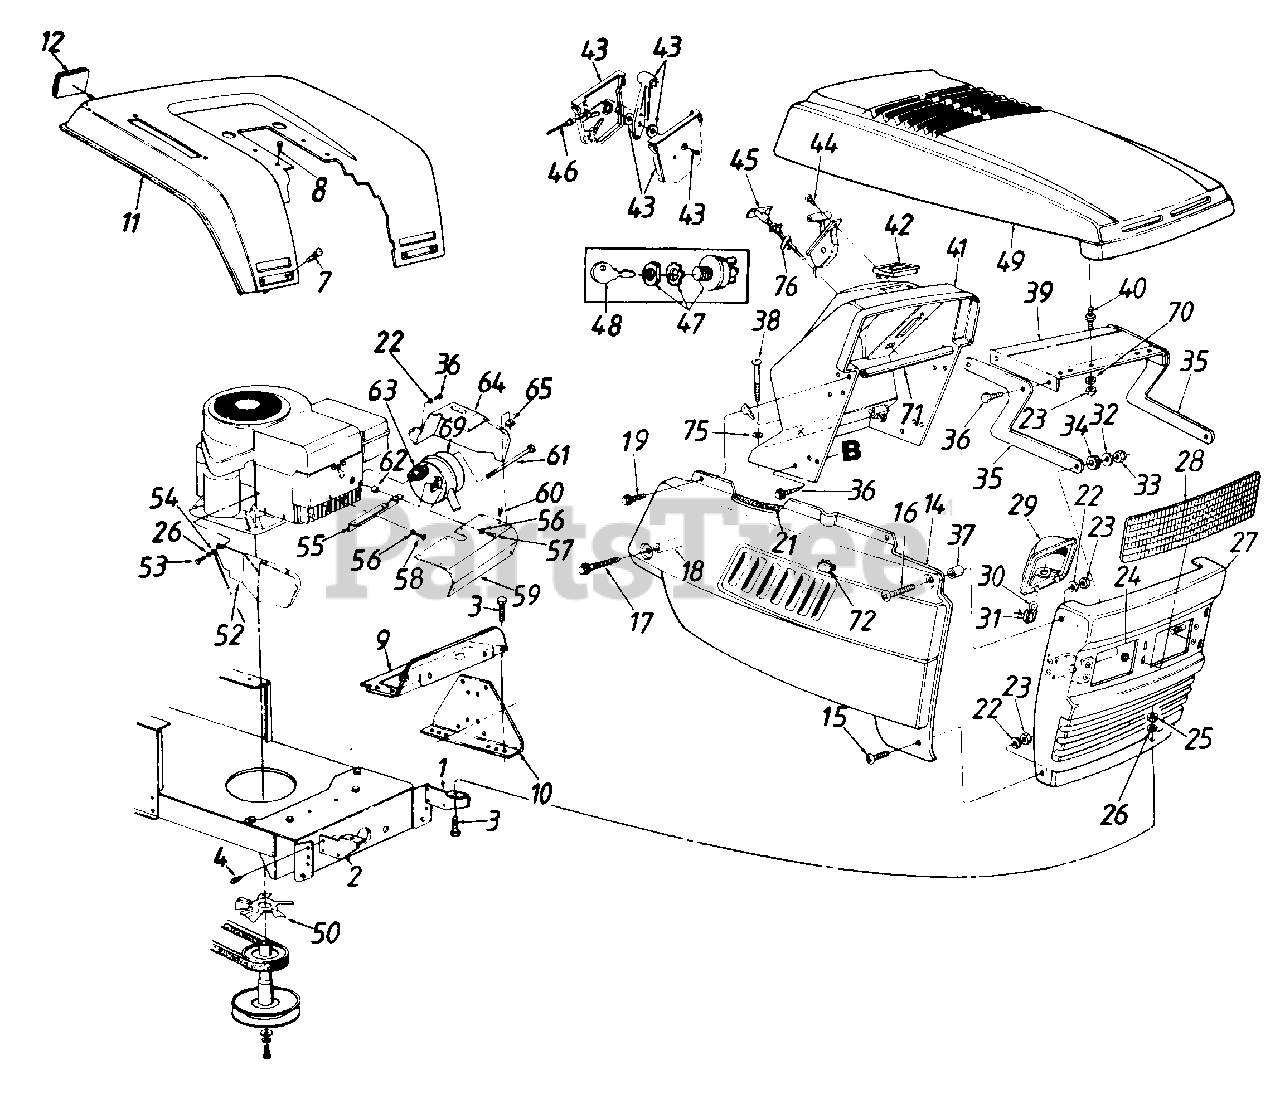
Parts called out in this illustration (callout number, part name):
1	Grille Mtg. Brkt. L.H.
4	Hex Wash. Hd. Tap Scr. 5/16-18 x .5" Lg.
7	Carriage Bolt 1/4-20 x .5" Lg.
8	Hex Wash. Hd. Tap Scr. 5/16 x .75" Lg.
9	Support Bracket
14	Side Panel R.H.
15	Truss Mach. Scr. 1/4-20 x .5" Lg.
16	Truss Mach. Scr. 1/4-20 x 1.0" Lg.
17	Hex Wash. TT-Tap Scr. 1/4-20 x 1.75" Lg.
18	Spacer .26" I.D. x 1.32
19	Hex Rolling Tap Scr. 1/4-20 x .75" Lg.
21	Trim Strip 12" Lg.
22	L-Wash. 1/4" I.D.
23	Hex Nut 1/4-20 Thd.
24	Speed Nut 5/16" Thd.
25	Hex Nut 5/16-18 Thd.
26	L-Wash. 5/16" I.D.
29	Headlamp Housing
30	Headlamp
31	Twist Lock Lamp Socket
32	Bell-Wash. .345" I.D. x .88"
33	Hex L-Nut 5/16-18 Thd.
34	Rubber Washer
35	Hood Hinge
36	Hex Wash. Hd. B-Tap Scr. 1/4-20 x .5" Lg.
37	Spacer .262" I.D. x .31"
38	Carriage Bolt 1/4-20 x 1.25" Lg.
39	Hood Plate
40	Double Ended Stud 1/4-20 Thd.
41	Dash
42	Ammeter
43	Throttle Control Box Ass'y.
44	Mach. Scr. #10 x .44" Lg.
45	Choke Control
46	Throttle Control Wire
47	Ignition Switch
48	Ignition Key
52	Muffler Heat Shield R.H.
53	Truss Mach. Scr. 5/16-18 x .75" Lg.
54	Ground Wire
55	Heat Shield Bracket
56	Spr. Wash. 1/4" I.D.
57	Hex Bolt 1/4-20 x .85" Lg.
58	Hex Bolt 1/4-20 x 3/8" Lg.
59	Muffler Heat Shield Front
60	Hex AB-Tap Scr. #10 x .5" Lg.
61	Shoulder Bolt
62	Spacer
63	Exhaust Gasket
64	Muffler Heat Shield L.H.
65	Speed Nut #10-24 Thd.
69	Muffler
70	Bell-Wash. .265" I.D. x .75"
71	Grille Support Tube
72	Mounting Clamp
75	Retaining Nut
76	Choke Retainer
